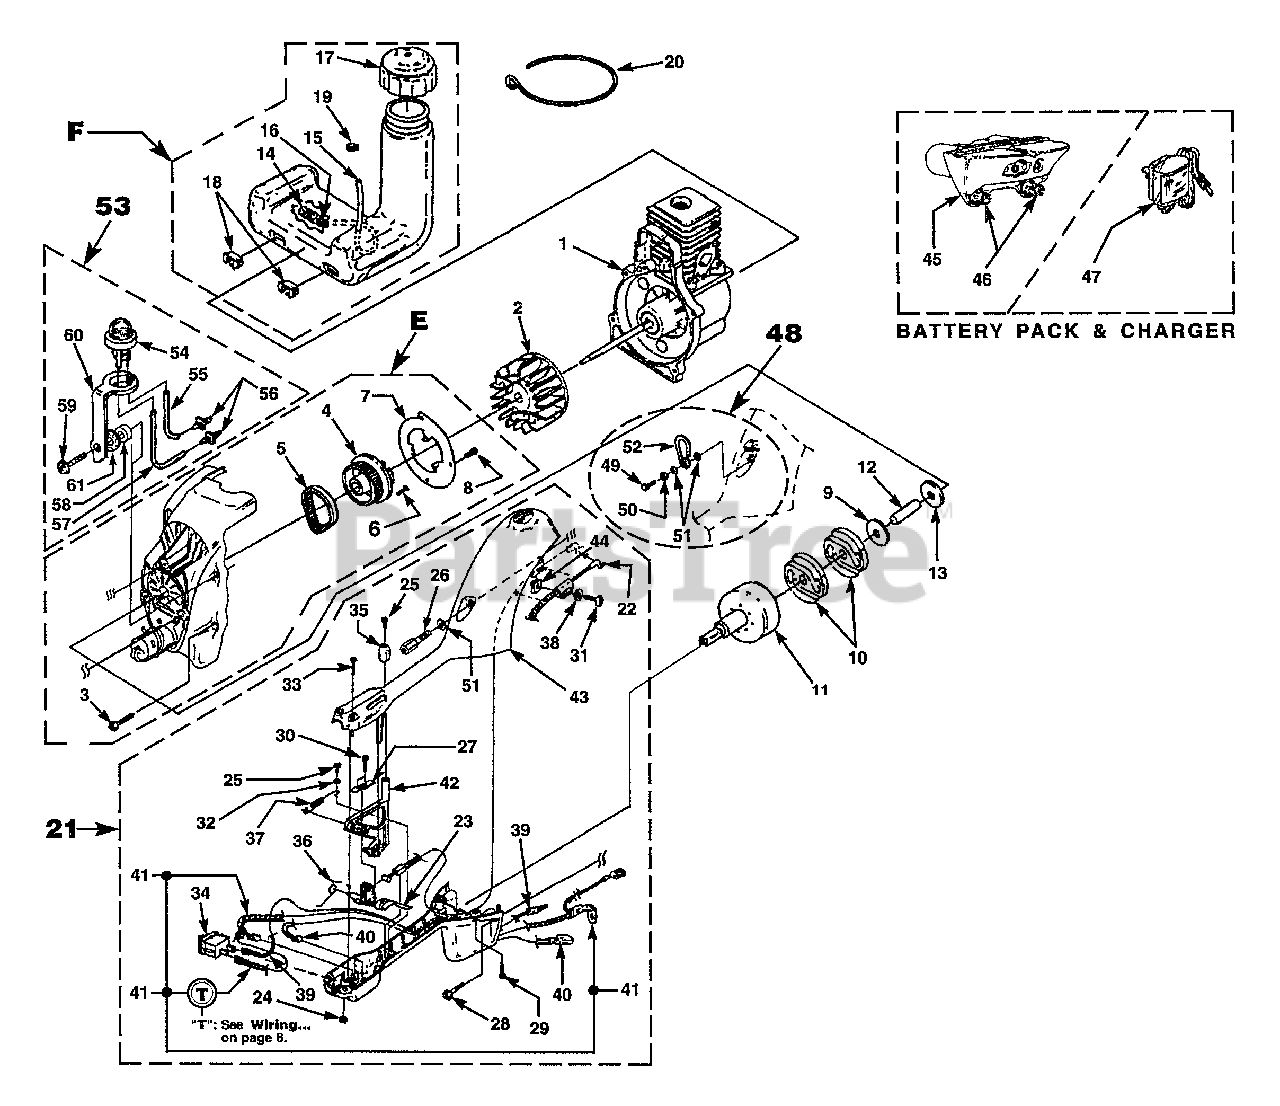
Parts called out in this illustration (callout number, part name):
1	SHORT BLOCK
2	ROTOR w/Starter Pawls
3	SCREW-Thread Form. (10-24 X 3/4")
4	PULLEY-Starter
5	BELT-Starter
6	SCREW- Thread Forming (8-32 X 1")
7	BAFFLE
8	SCREW-Plastite (8-16 1/2")
9	WASHER-Flat
11	CONNECTOR & DRUM
12	SPACER
14	FILTER-Fuel
15	TUBING-Rubber (5")
16	CLAMP-Wire
17	FUEL CAP
18	BUMPER-Rubber
19	FITTING-In Line Fuel
20	SUPPORT WIRE
21	CLUTCH HOUSING & CONTROL HANDLE
22	CABLE-Throttle
23	TRIGGER
24	NUT-Hex (10-24)
25	SCREW-Thread Forming (#4-20 X 1/4")
26	SCREW-Adaptor
27	RETAINER
28	SCREW-Torx Truss Hd. (#10-24 X 1 1/4")
29	SCREW-Thread Forming (#10-14 X 1/2")
30	SCREW-Thread Forming (#6-20 X 1/2")
31	SCREW-Socket Head
33	SCREW-Truss Hd. (#10-24 X 1 7/8")
34	SWITCH-Rocker (Domestic)
35	KNOB-Starter Lever
36	SPRING-Torsion
37	SPRING-Extension
38	WASHER-Flat
39	LEAD-Electrical
40	LEAD-Electrical
41	LEAD-Electrical
42	STARTER LEVER w/BAR
43	CLUTCH HOUSING (Top)
44	NUT-Tinnerman
45	BATTERY PACK
46	KNOB-Battery Pack
47	CHARGER-Battery Pack
48	HANGER KIT
50	WASHER-Lock
53	START ASSIST BUTTON KIT
54	BUTTON-Start Assist
55	LINE-Fuel (2.0") (5,0cm)
56	FITTING-Fuel Line
57	LINE-Fuel (2.5") (6,5cm)
58	SPACER
59	SCREW- (10-24 x 1.00")
60	BRACKET
61	WASHER-External Lock
E	COMPLETE STARTER ASSEMBLY
F	FUEL TANK COMPLETE
